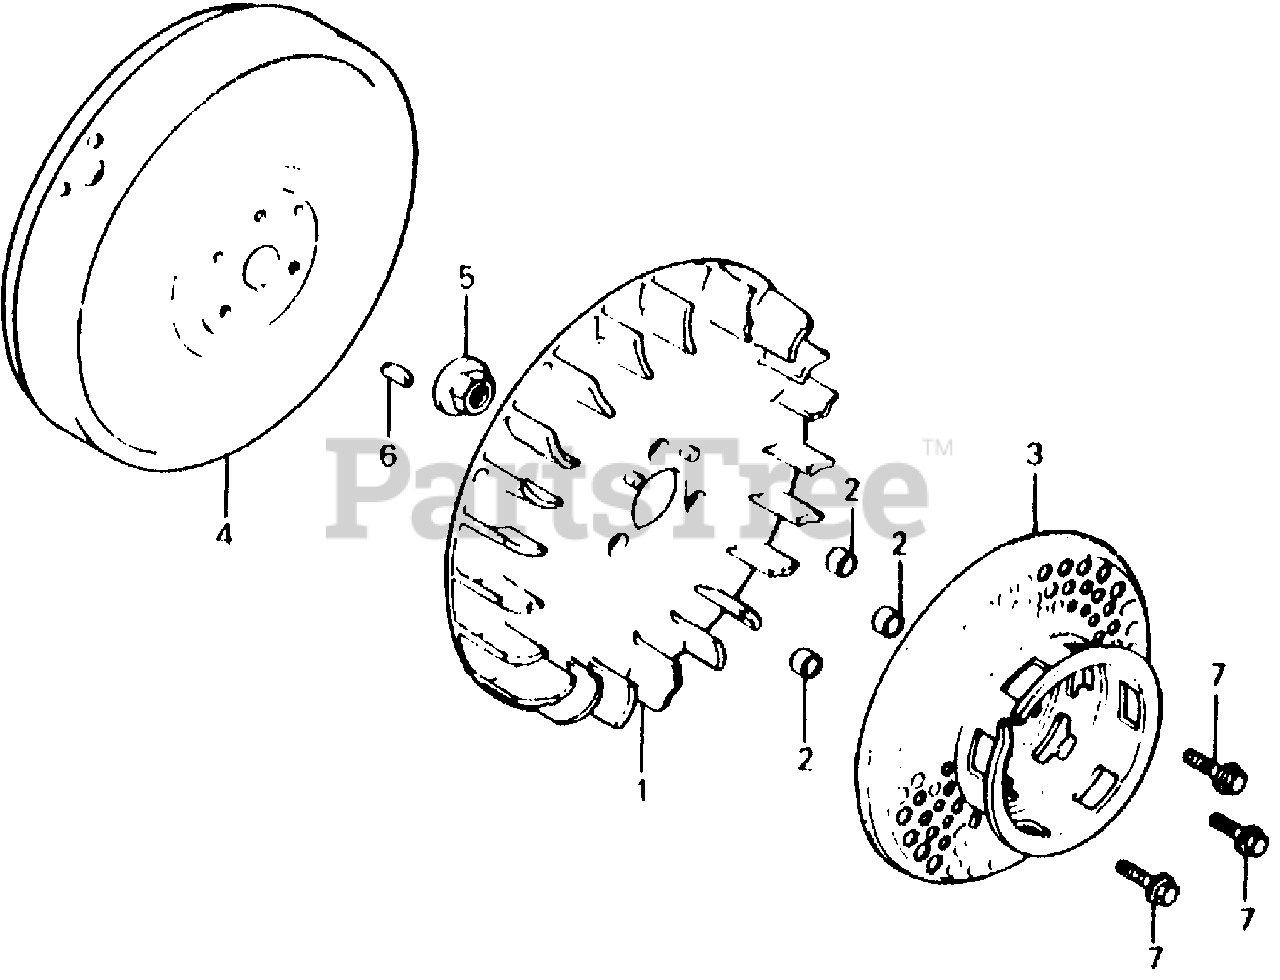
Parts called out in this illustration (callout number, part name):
1	FAN, COOLING
2	COLLAR, FAN
3	PULLEY, STARTER
5	NUT, SPECIAL (16MM)
6	KEY, SPECIAL WOODRUFF (25X18)
7	BOLT, FLANGE (6X16)
